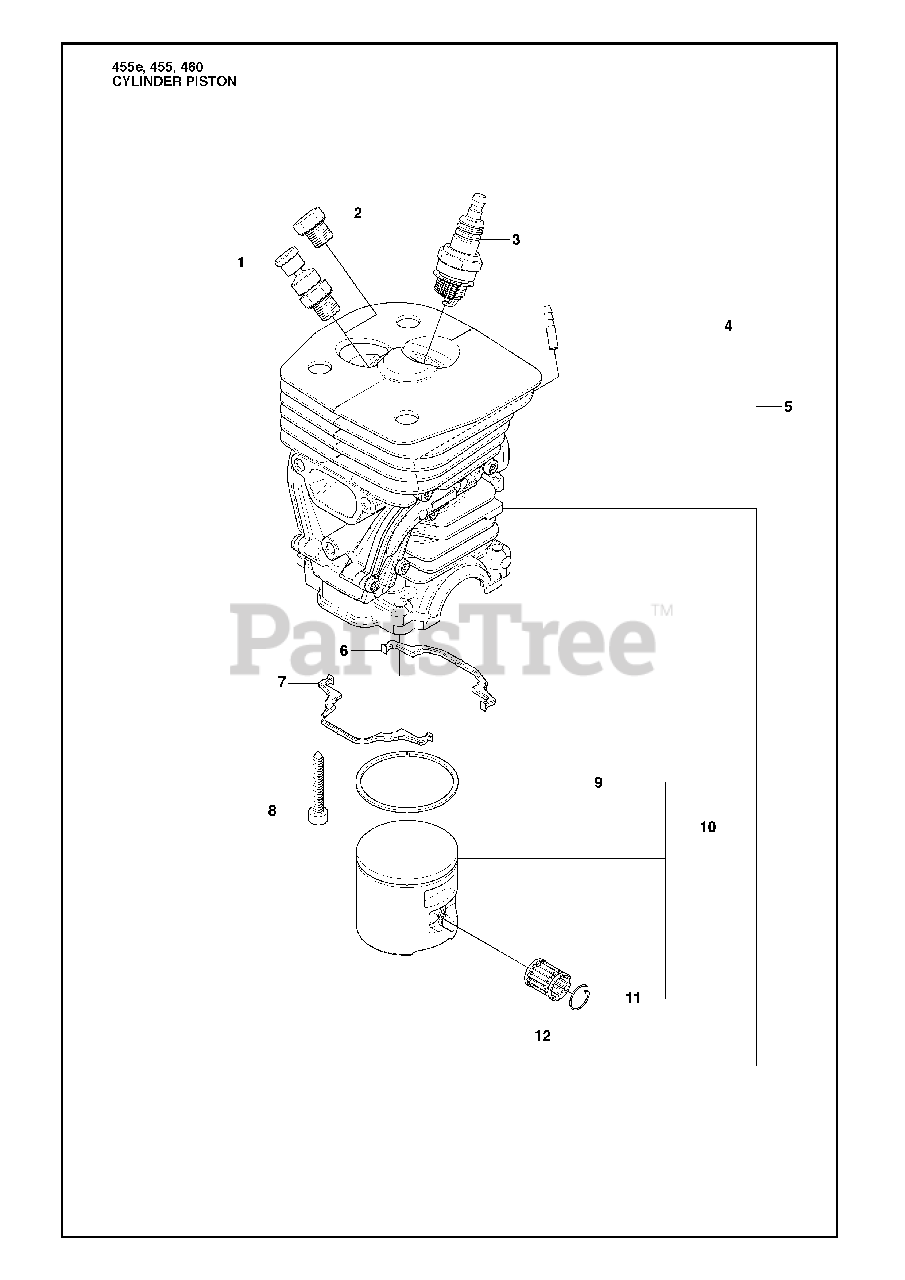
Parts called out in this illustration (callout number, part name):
1	RP VALVE
2	CYLINDER PLUG
3	SPARK PLUG RCJ7Y
5	CYLINDER
9	PISTON RING
10	PISTON CPL.
10	PISTON
11	WRIST PIN CLIP
12	SUPPORT BUSHING
